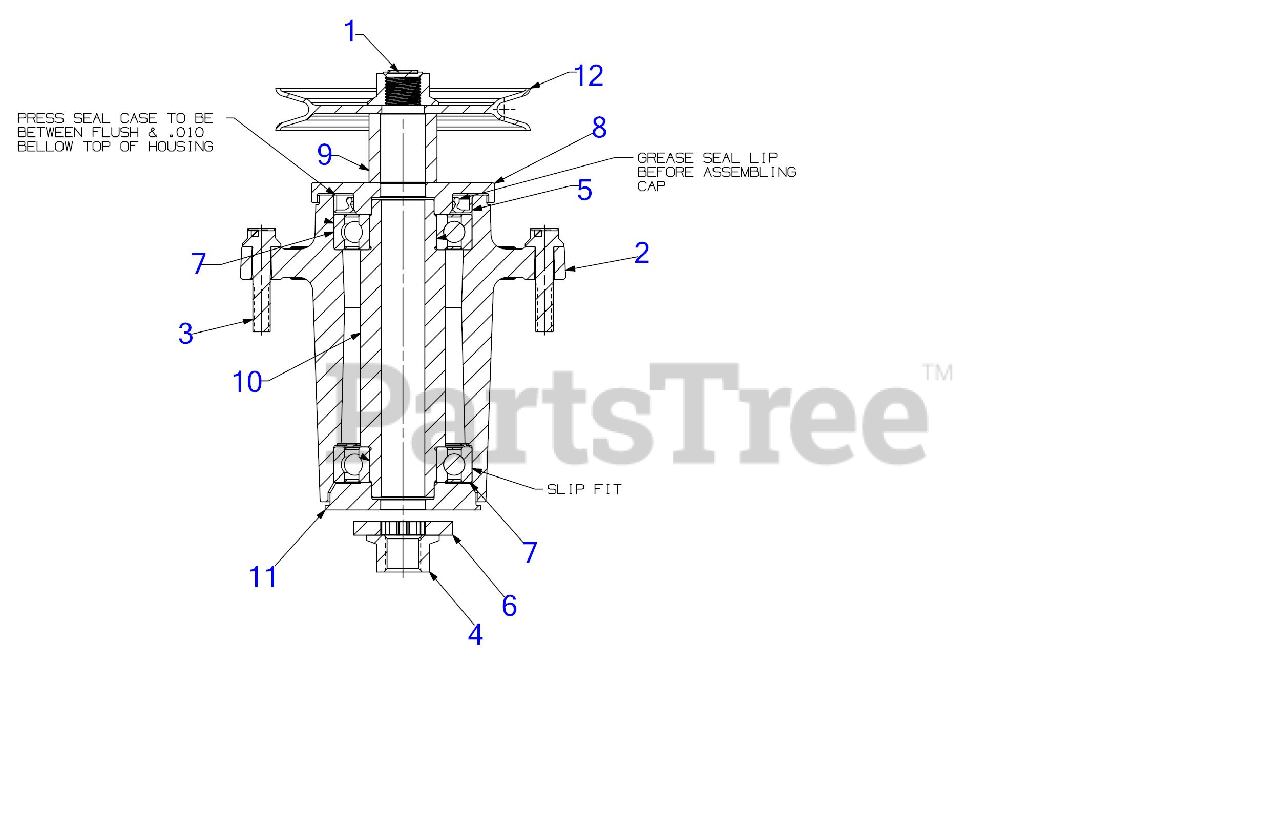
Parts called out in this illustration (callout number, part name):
1	SPINDLE SHAFT
2	SPINDLE HOUSING
3	BOLT 5/16-18 x 1.50 GR5
4	FLANGE NUT - 5/8-18 GDE 8
6	FLAT WASHER - SPECIAL
7	SEALED BALL BEARING 30x62x16
8	DECK SPINDLE SPACER
9	SPACER 0.760 X 1.50 X 1.24
10	SPACER 0.760 X 1.50 X 3.484
11	SPACER 0.790 X 2.75 X 0.486
12	PULLEY-4.50 OD
